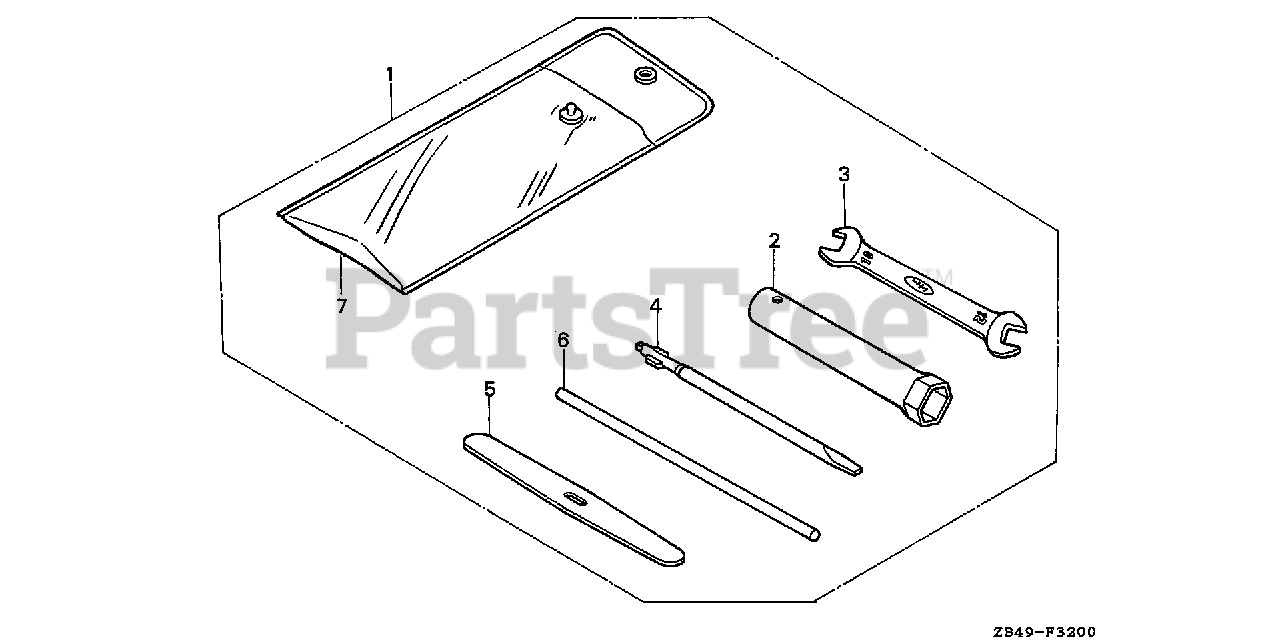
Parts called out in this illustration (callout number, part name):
2	WRENCH, PLUG
3	SPANNER (10X12)
4	DRIVER 3, MINUS SCREW (NO.2)
6	BAR A, HANDLE
